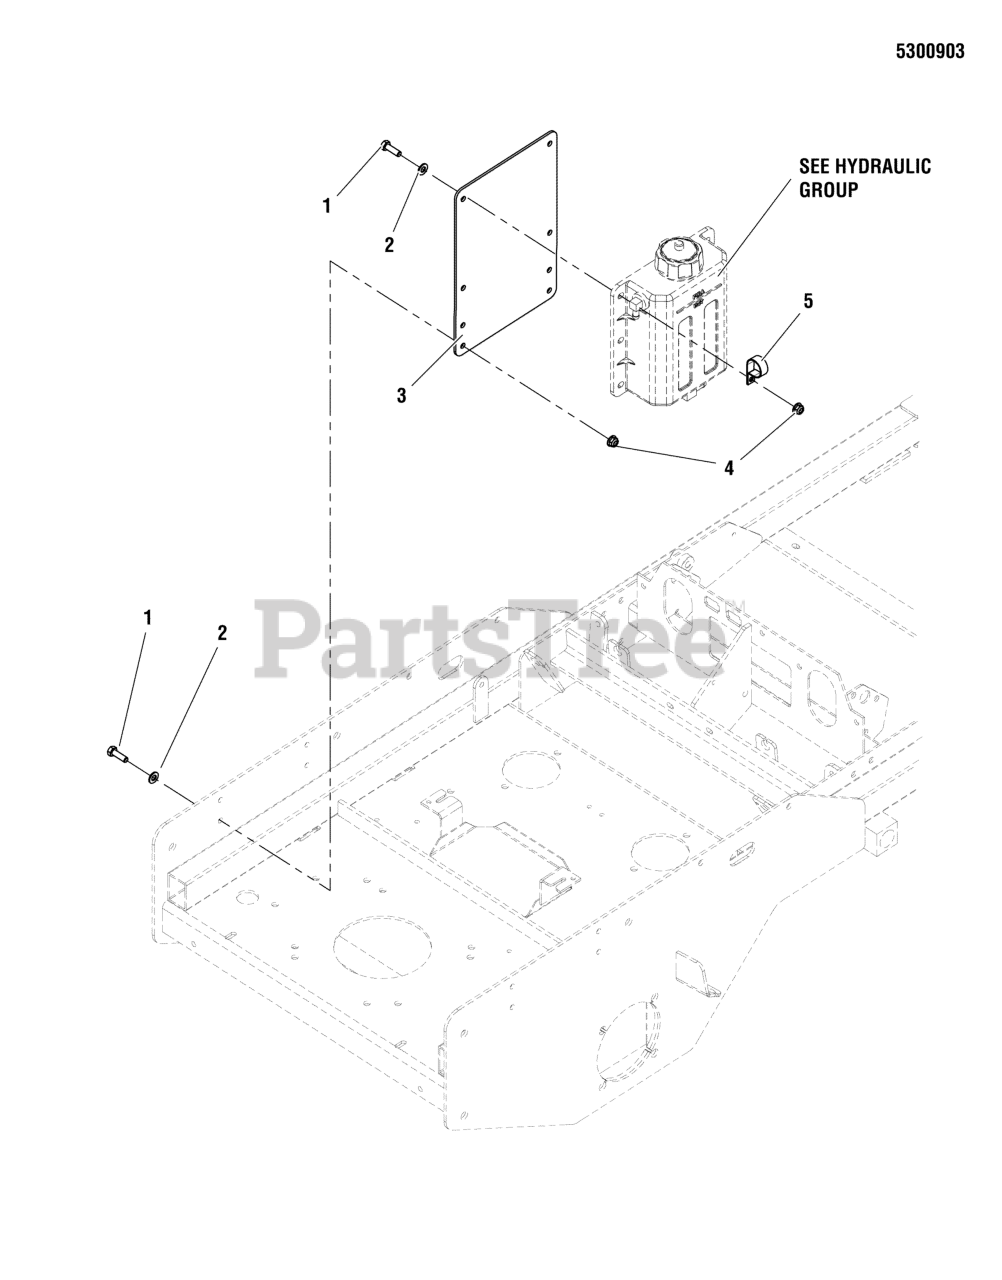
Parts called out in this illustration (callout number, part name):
1	BOLT, 5/16-18 X 1 GD5 YZ
2	WASHER, 5/16" SAE
3	PLATE, MOUNT, RESERVOIR - RED
4	NUT, 5/16-18 HEX NYLOCK FLANGE
5	CLAMP, HOSE, 1.000 DIA.
